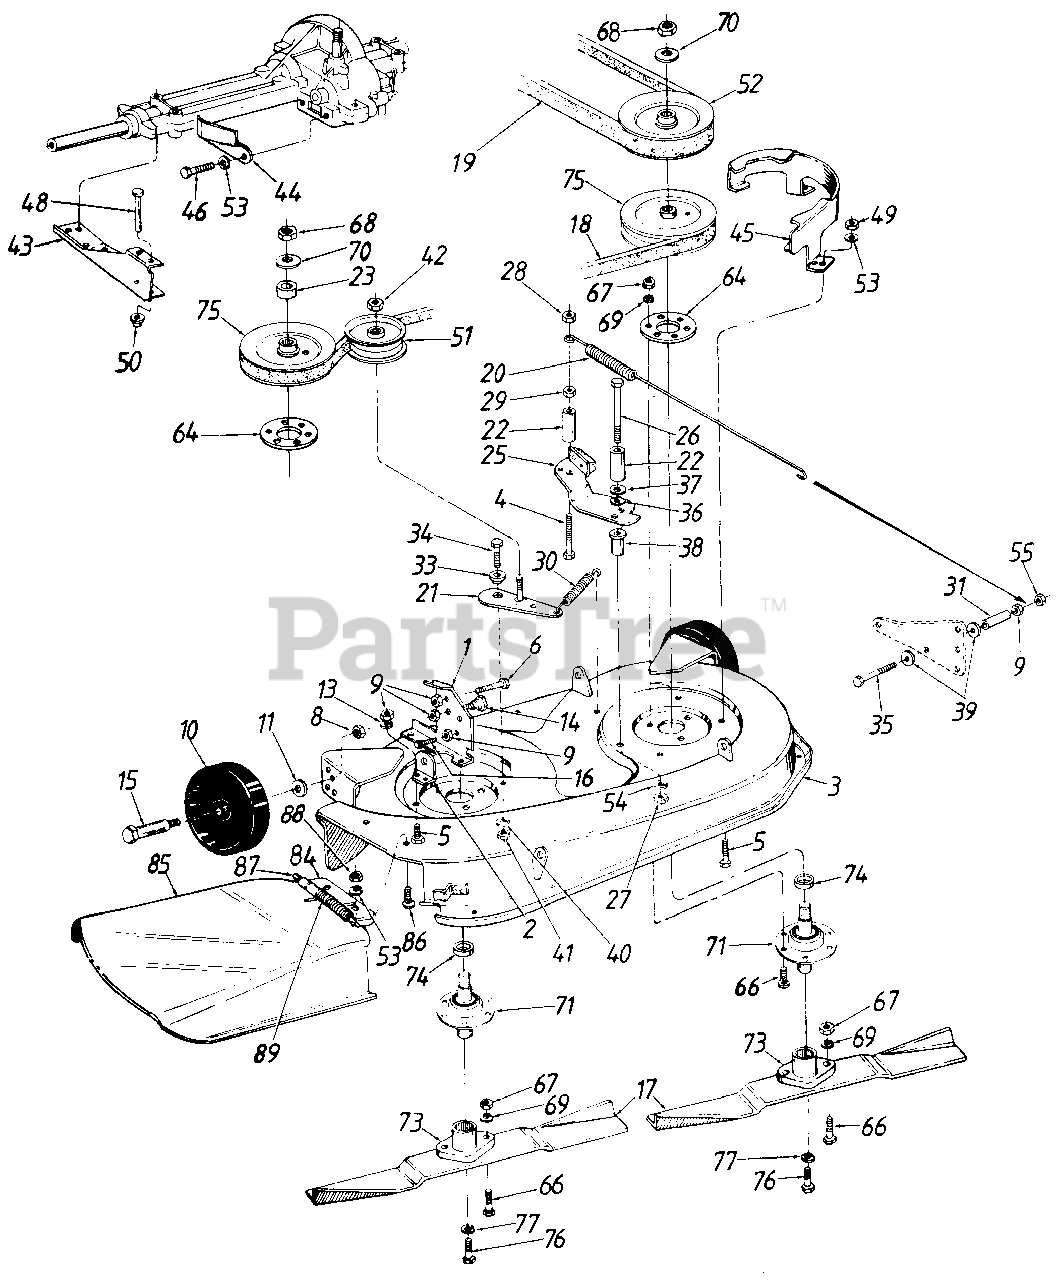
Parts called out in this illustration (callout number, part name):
1	Deck Disengagement Brkt.
2	Rear Deck Brkt.-R.H.
3	32" Deck Ass'y.
4	Hex Bolt 1/4-28 x 1.75" Lg.
5	Hex Bolt 1/4-20 x .62" Lg.
6	Hex Wash. Hd. Scr. 1/4-20 x 1.5" Lg.
8	Hex L-Nut 3/8-16 Thd.
9	Hex Nut 1/4-20 Thd.
10	Deck Wheel
11	Bell-Wash 380" I.D. x .88"
13	L-Wash 1/4 I.D.
14	Shld. Bolt .500" Dia. x .215"
15	Shld. Bolt .498" Dia. x 1.53
16	Hex Tap Scr. 1/4-20 x .75" Lg.
17	R.H. High-Lift Blade
18	V-Belt
19	V-Belt
20	Extension Spring 15-5/8" Lg.
21	Idler Brkt. Ass'y.
22	Spacer 5/16" I.D. x 1/2" O.D. x 31/32"
23	Spacer .752" I.D. x 1.25" O.D.
25	Deck Brake Brkt. Ass'y.
26	Hex Bolt 5/16-18 x 3.25" Lg.
27	Hex Nut 5/16-24 Thd.
28	Hex L-Nut 1/4-28 Thd.
29	Hex Nut 1/4-28 Thd.
30	Extension Spring 4.35" Lg.
31	Spacer 1/4" I.D. x 3/8" O.D. x 1-5/16"
33	Shoulder Spacer
34	Hex Bolt 3/8-16 x 1 Lg.
35	Hex Bolt 1/4-20 x 2.5" Lg.
36	Wave Washer
37	Shld. Spacer .27" Lg.
38	Spacer 1.46" Lg.
39	Flat Wash. 1/4"
40	L-Wash. 3/8" I.D.*
41	Hex Nut 3/8-16 Thd.
42	Hex L-Nut 3/8-24 Thd.
43	Lower Outside Belt Guard
44	Lower Inside Belt Guard
45	Belt Guard Deck-R.H.
46	Hex Bolt 1/4-20 x .62" Lg.*
49	Hex Nut 1/4-20 Thd.*
50	Speed Nut 1/4" Rod
51	Flat Idler Pulley
52	5" Dia. Pulley
53	L-Wash. 1/4" I.D.*
54	Bell-Wash. 5116" I.D.
55	Hex L-Nut 1/4-20 Thd.
64	Reinforcement Plate
66	Hex Bolt 5/16-24 x 1" Lg.
67	Hex Nut 5/16-24 Thd.*
68	Hex Jam Nut 5/8-18 Thd.
69	L-Wash. 5/16" I.D.*
70	Bell-Wash. 5/8" I.D.
71	Blade Spindle Ass'y. Comp.
73	Blade Adapter
74	Spacer
75	5" Dia. Pulley
76	Hex Bolt 3/8-24 x 1.0" Lg.
77	L-Wash. 3/8" I.D. H.D.
84	Chute Bracket
85	Chute
86	Truss.-Mach. Scr. 1/4-20 x .75" Lg.
87	Hinge Pin
88	Hex Nut 1/4-20 Thd.*
89	Torsion Spring 1.14" Lg.
